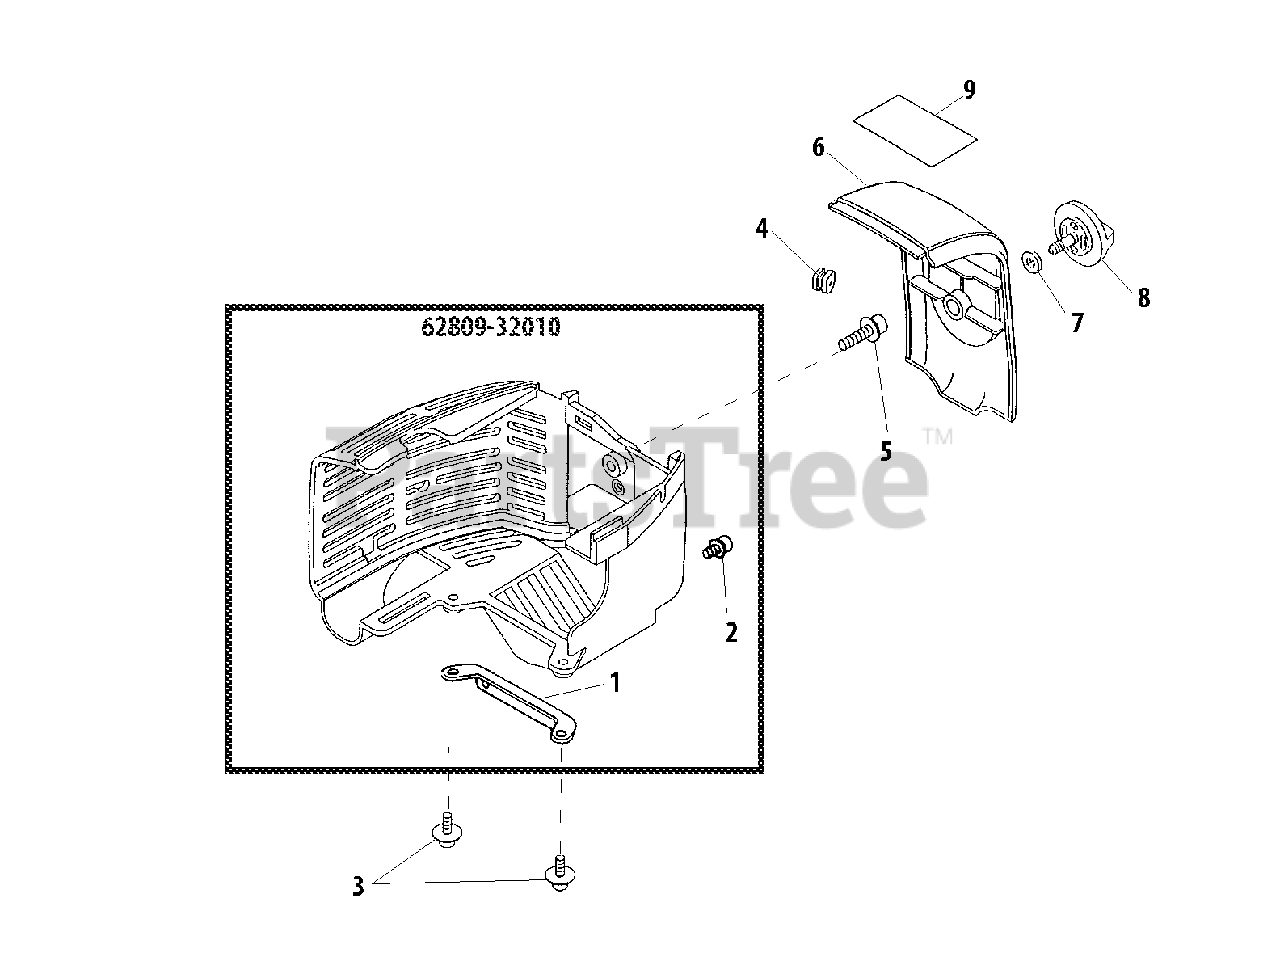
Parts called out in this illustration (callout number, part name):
1	BRACKET
2	SCREW - 5X10
3	SCREW - 4X12
4	GROMMET
5	SCREW - 5X20
6	COVER
7	WASHER - VINYL
8	THUMBSCREW
9	LABEL - MODEL
62809-32010	ENGINE COVER KIT
